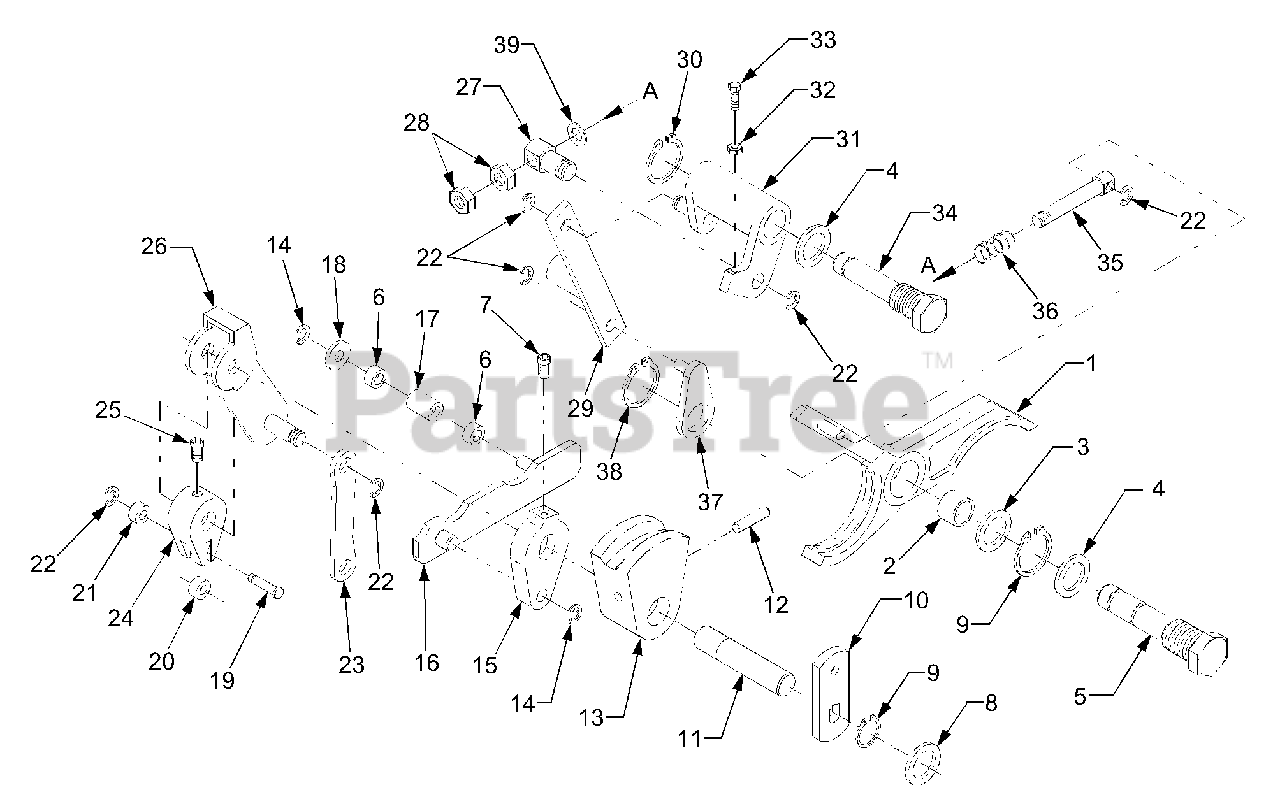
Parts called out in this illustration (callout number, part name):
2	Bearing, Needle
18	Washer, Plain
39	Washer, Plain
